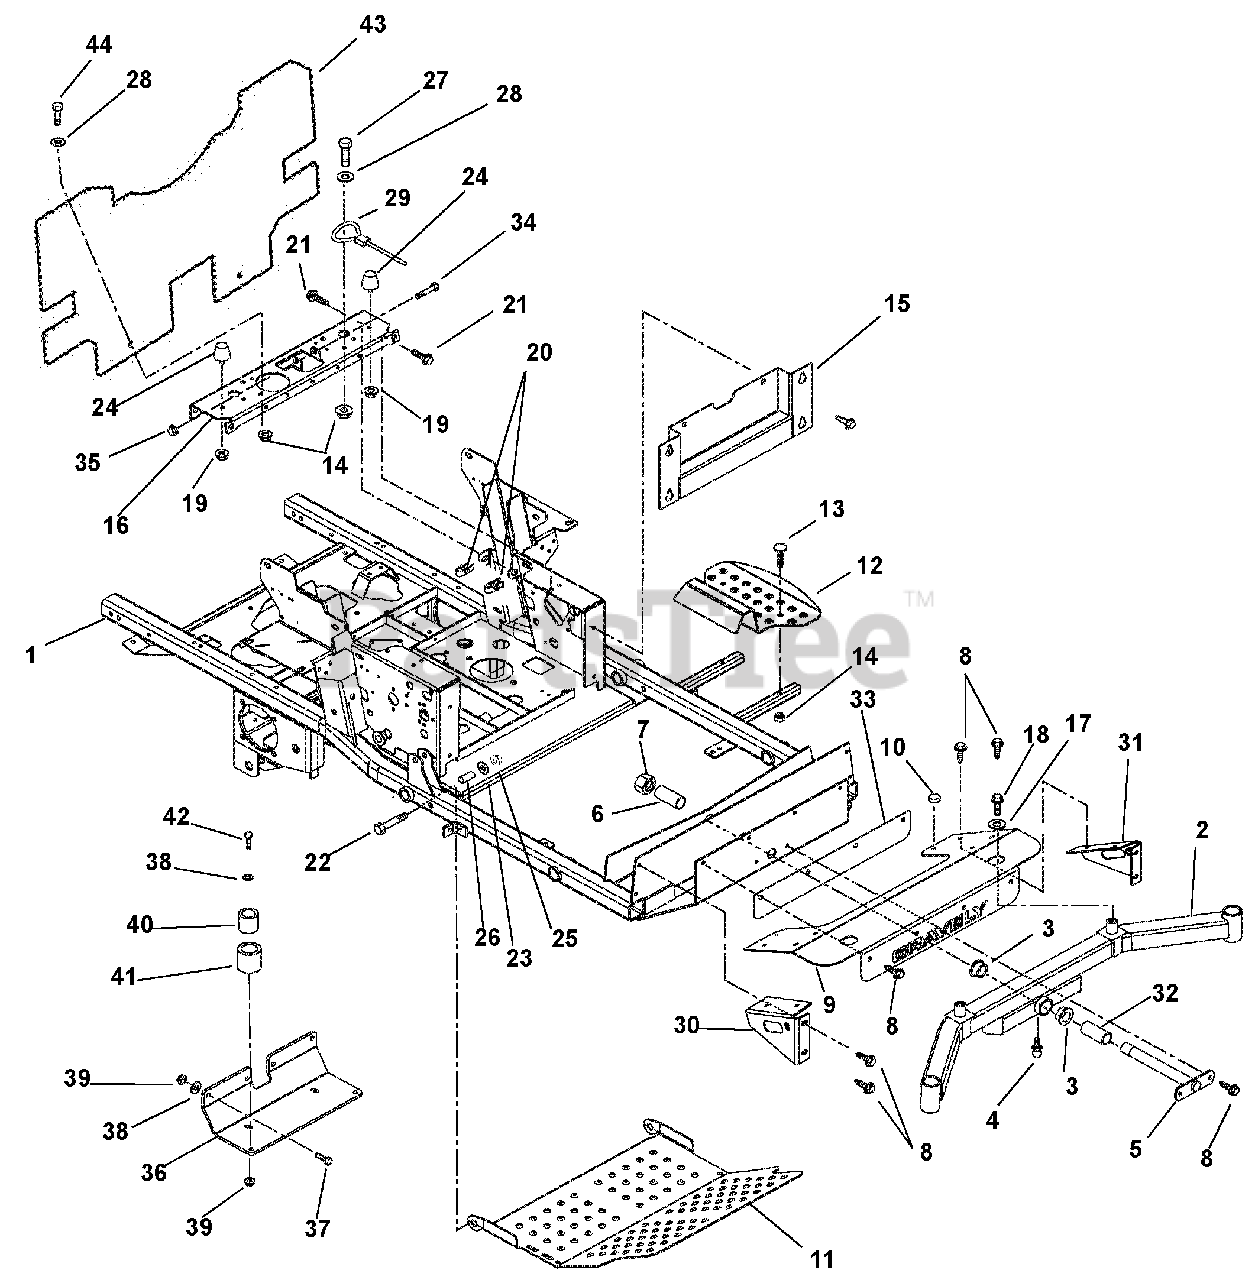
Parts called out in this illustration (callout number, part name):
1	Weldment, Frame
2	Weldment, Axle
3	Bushing, Flange 1.25 x 1.50 x 1.00 x .200
4	Fitting, Lube 45 Degree GM411031
5	Pin, Axle
7	Nut, Locking Nylon 1.00-14
8	Screw, Tapping .38-16 x .75
9	Axle Cover
10	Button, Rubber
11	Panel, Inspection
12	Step, Ingress
13	Bolt, Round Head Square Neck .31-18 x 1.75 Grade 5
14	Nut, Locking Top Flange .31-18
15	Plate, Kick
16	Channel, Cross
17	Washer, Flat Steel .640 x 1.81 x .25
18	Bolt, Hex .50-20 x 1.00 Grade 5
19	Nut, Locking Flange .312-18
20	Nut, Retainer .375-16 x .37
21	Bolt, Serrated Hex Flange Washer Head .38-16 x 1.00
22	Bolt, Hex .50-13 x 3.25 Grade 5
23	Washer, Flat Steel .563 x 1.38 x .109
25	Nut, Locking Top Flange .50-13
26	Bushing, Flange .515 x .75 x .275 x 1.12
27	Bolt, Hex .31-18 x .75 Grade 5
28	Washer, Flat Steel .344 x 1.25 x .135
29	Cable, Seat Prop
30	Weldment, Right Axle Cover Support
31	Weldment, Left Hand Axle Cover Support
32	Spacer, 1.25OD x 1.0ID x 3.63
33	Plate, Backer
34	Bolt, Hex .38-16 x 3.00 Grade 5
35	Nut, Locking Top Flange .38-16
36	Bracket, Support Arm Frame (992219)
37	Bolt, Hex .50-13 x 1.25 Grade 5 (992219)
38	Washer, Flat Steel .531 x 1.06 x .095 (992219)
39	Nut, Locking Top Flange .50-13 (992219)
40	Spacer, .563 x 1.25 x .969 (992219)
41	Spacer, .563 x 2.00 x 2.00 (992219)
42	Bolt, Hex .50-13 x 4.50 Grade 5 (992219)
43	Guard, Grass (992219)
44	Bolt, Hex .31-18 x 1.00 Grade 5 (992219)
